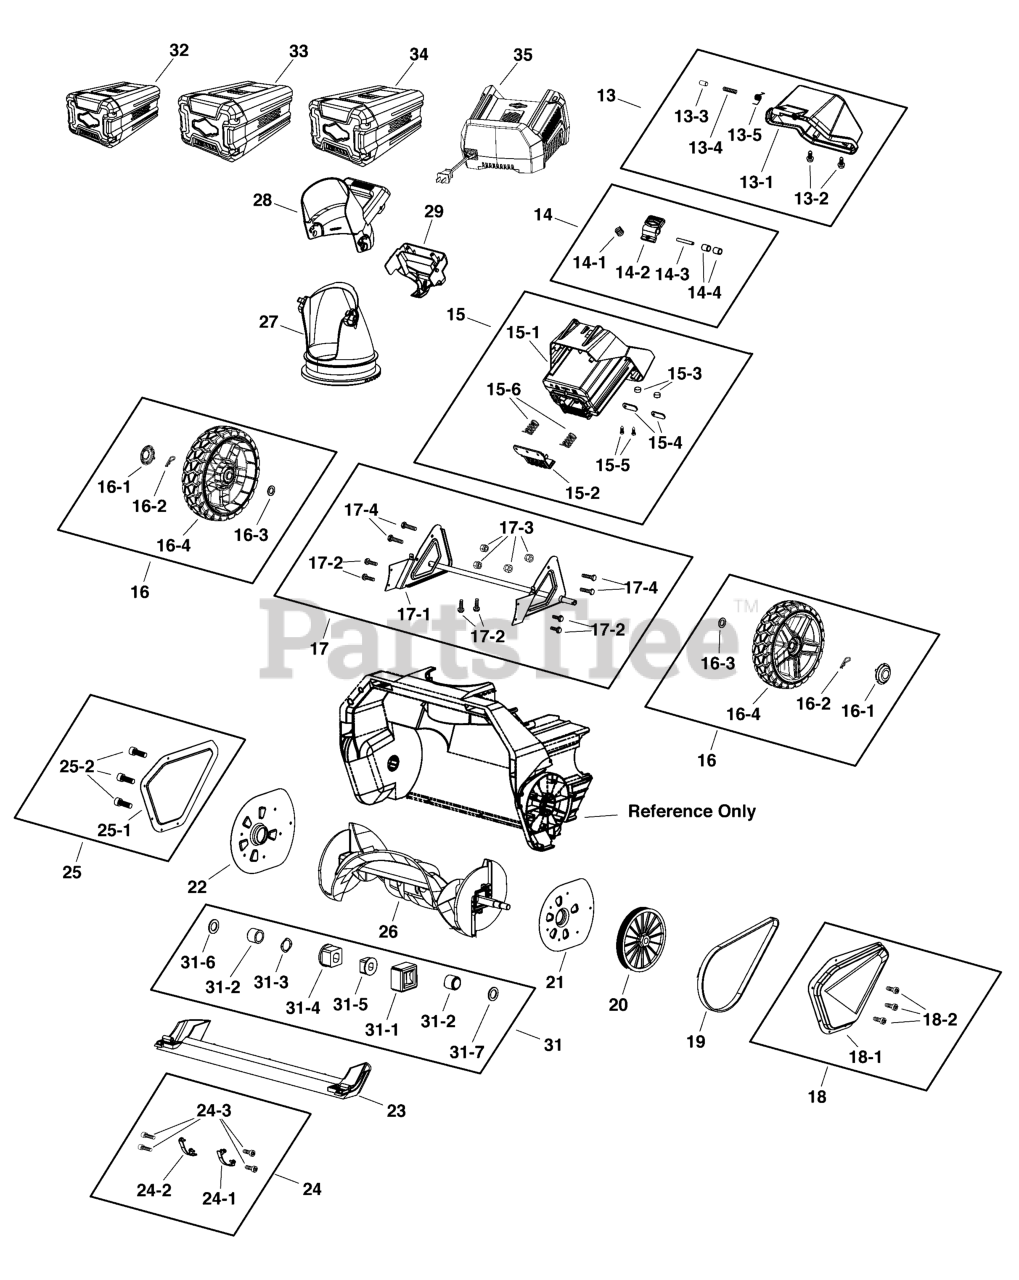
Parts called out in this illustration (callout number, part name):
13	KIT, Battery Cover
13-1	COVER, Battery
13-3	PIN
13-4	SPRING, Compession
13-5	SPRING, Torsion
14	KIT, Release Lever
14-1	SPRING, Compession
14-2	BUTTON, Battery Releasee
14-3	PIN
14-4	AXLE SLEEVE
15	KIT, Battery Compartment
15-1	COMPARTMENT, Battery
15-2	TERMINAL
15-3	MAGNET
15-4	PLATE
15-6	SPRING, Compession
16	KIT, Wheel
16-1	COVER, Wheel
16-2	PIN, Cotter
16-3	GASKET
17	KIT, Axle
17-1	AXLE
18	KIT, Left Cover
18-1	COVER, Left
19	BELT, Auger
20	PULLEY, Belt
21	PLATE, Left, Auger
22	PLATE, Right, Auger
23	BAR, Scraper
24	PLATE, Wear
24-1	SKID SHOE, Left
24-2	SKID SHOE, Right
25	KIT, Right Cover
25-1	COVER, Right
26	KIT, Auger Assembly
27	KIT, Chute Assembly
28	KIT, Deflector
29	KIT, Lever, Discharge Chute
31	KIT, Bushing, Auger
31-1	BEARING
31-2	SLEEVE
31-3	GASKET
31-4	GEAR
31-5	GEAR
31-6	GASKET
31-7	GASKET
32	* BATTERY, 2.0, 82V NA
33	* BATTERY, 4.0, 82V NA
34	* BATTERY, 5.0, 82V EU/AU
35	* CHARGER, Battery, NA
